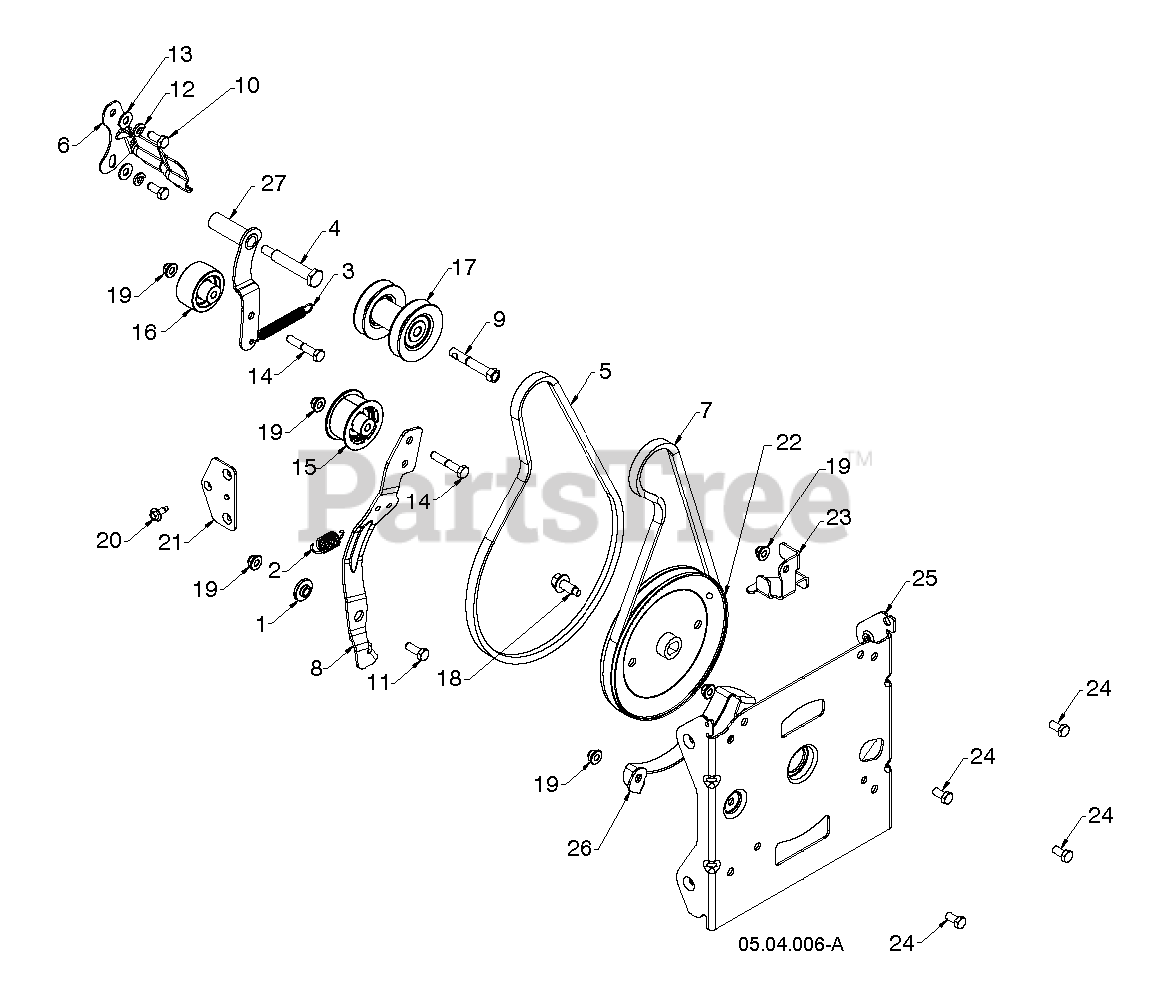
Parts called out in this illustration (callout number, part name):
1	BUSHING.BRAKE.ARM
2	SPRING RETURN, IDLER ARM, IMPE
3	SPRING RETURN IDLER ARM
4	BOLT 5/16-24X2.25 HEX HEAD SHO
5	BELT.HIGH.CRANK.4LX41.RAW.EDGE
6	BELT KEEPER BRACKET
7	HIGH CRANK IMPELLER BELT
8	ARM.IDLER.AUTO-PH.676
9	BOLT.ENGINE.PULLEY
10	SCREW 5/16-24 X .75 GR5
11	BOLT HEXAGON BOLT 5/16-18 X 7/
12	WASHER SPRING LOCK WASHER WITH
13	WASHER 11/32 X 11/16 X 14 GA T
14	BOLT, HEX 5/16-18X1-3/4
15	PULLEYIDLER.2.0.W/SPACER.CZ
16	PULLEY.IDLER.FLNGLESS.W/SPACER
17	PULLEY.ASM.IMPELLER/DRIVE
18	SCREW HEXAGON HEAD FLANGE 3/8-
19	NUTNYLOK.FLRANGE.5/16-18
20	HEX.WASHER.HEAD 1/4-20 X .65
21	BRACKET NUT BLACK ZINC PLATE
22	PULLEY IMPELLER DD 4L
23	GUIDE.LOWER.AUGER.BELT.479
24	BOLT, HEX HEAD 5/16-18
25	BRACKET.AUG.HOUSING.INTER.BLAC
26	BRACKET.BELT.KEEPER.LOWER.BLAC
27	ARM IDLER DRIVE WELDMENT_HOT
